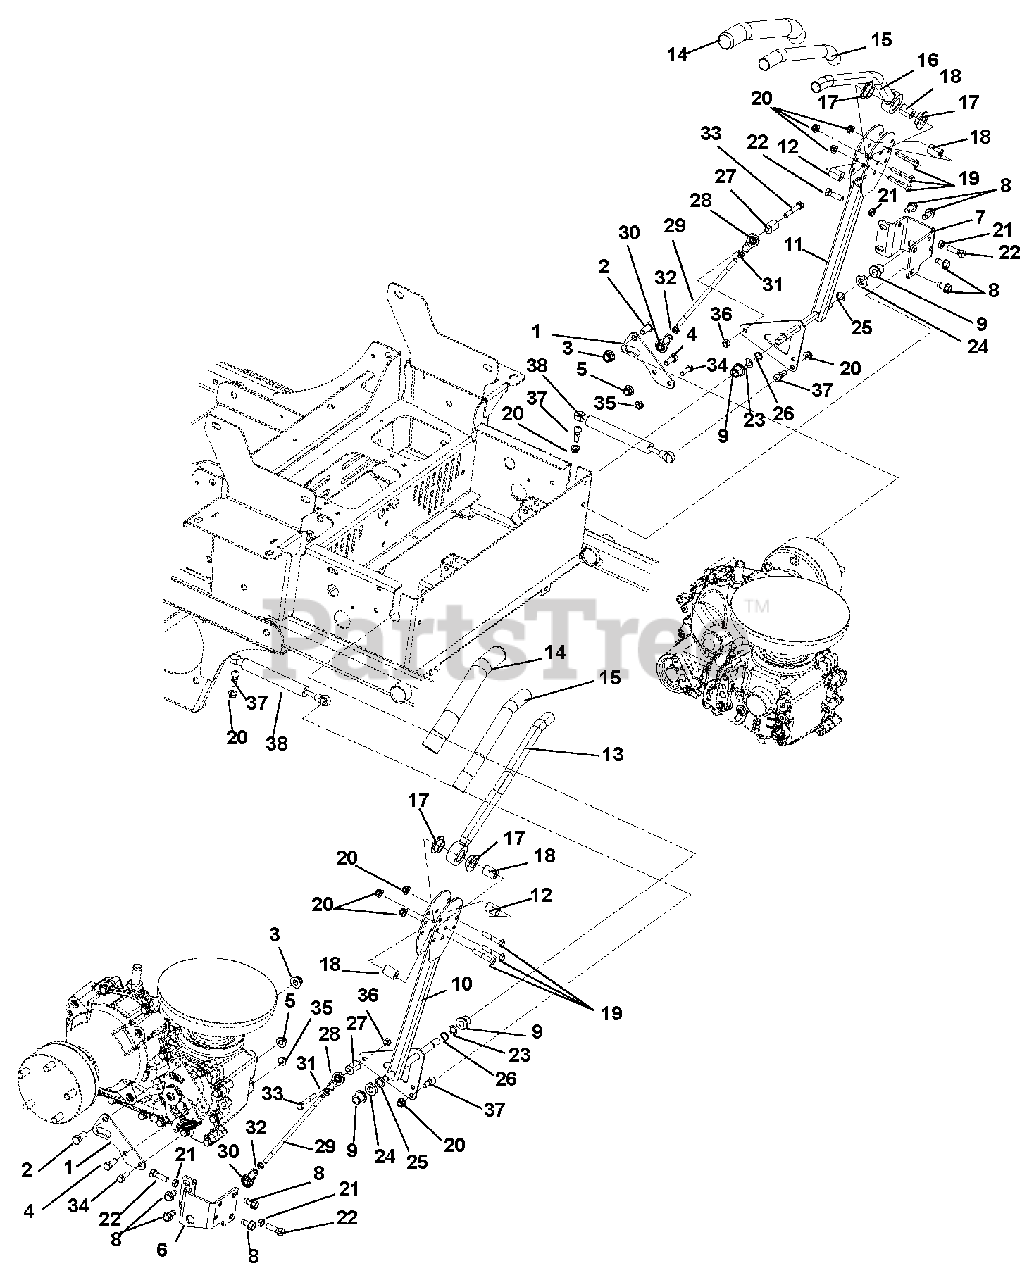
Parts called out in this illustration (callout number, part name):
1	Bracket, Control Mounting
2	Bolt, Hex .44-14 x 1.00 Grade 5
3	Nut, Locking Nyloc Flange .44-14
4	Bolt, Hex .38-16 x 1.00 Grade 5
5	Nut, Locking Nyloc Flange .38-16
6	Bracket, Control Stop Right Hand
7	Bracket, Control Stop Left Hand
8	Screw, Tapping .38-16 x .75 Hex Washer Head
9	Bushing, Flange Nylon .515 x .750 x .745 x 1.00
10	Weldment, Control Arm Right Hand
11	Weldment, Control Arm Left Hand
12	Bushing, Eccentric .31 x .75 x .97
13	Handle Weldment Right Hand
14	Grip, Handlebar 1.00 x 1.38 x 11.3
15	Tube, .88 ID x 1.00 OD x 10.75
16	Handle Weldment Left Hand
17	Bushing, Flange Nylon .762 x 1.48 x .44
18	Spacer .328 x .76 x 1.01
19	Bolt, Hex .31-18 x 1.75 Grade 5
20	Nut, Locking Nyloc Flange .31-18
21	Nut, Hex Jam .375-16
22	Bolt, Hex .38-16 x 1.25 Grade 5
23	Washer, Flat Steel .520 x .810 x .033
24	Spacer .531 x 1.00 x .195
25	Wave Washer .531 x .781 x .125FH
26	Ring, Retaining External .500 x .050
27	Eccentric
28	Alignaball, 5/16 Right Hand Thread
29	Rod, Steering
30	Alignaball, 5/16 Left Hand Thread
31	Nut, Jam .31-24
32	Nut, Jam Left Hand .31-24
33	Bolt, Hex .31-18 x 2.00 Grade 5
34	Bolt, Hex .31-18 x 1.00 Grade 5
35	Nut, Locking Top Flange .31-18
36	Nut, Locking Center .31-18
37	Stud, Ball
38	Damper
